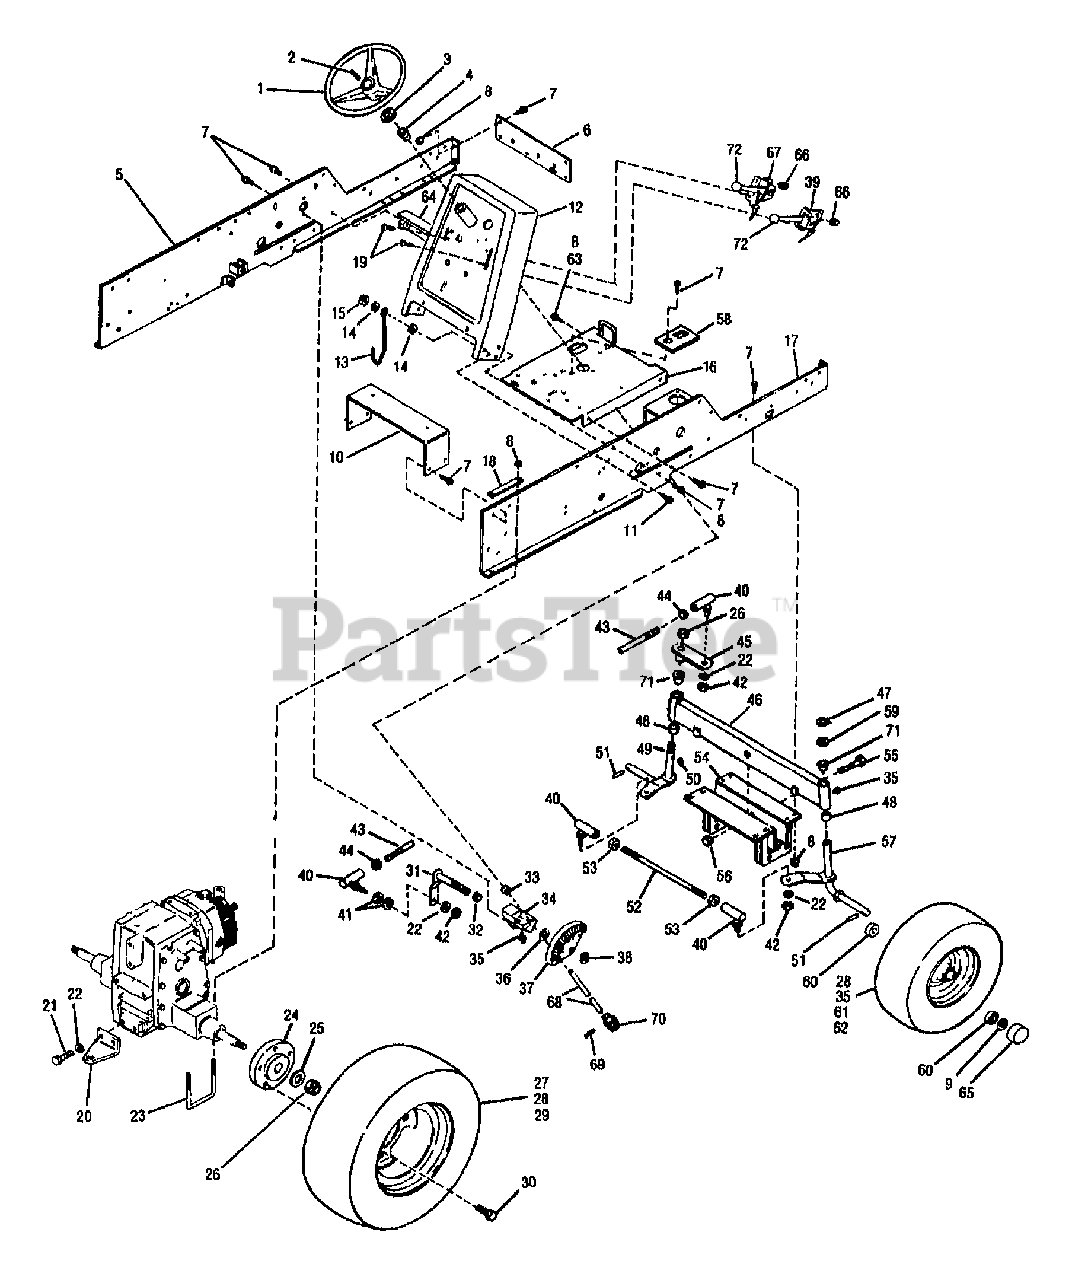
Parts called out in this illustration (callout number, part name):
1	WHEEL-STEERING
2	PIN-ROLL .25X2.25
3	WASHER-1.5X.755X.062
4	BEARING-STEERING
5	ASSM-FRAME LH
8	NUT-HFLK 3/8-16 ZP
9	WASHER-THRUST
10	SUPPORT-SEAT
11	SCR-HFLK 3/8-16X1.00 ZP
12	ASSM-INST PANEL
13	GUIDE-CABLE
14	WASHER-.986X.437X.083 ZP
15	NUT-H/LK 3/8-16
16	ASSM-SUPT BATTERY&GAS TANK
17	ASSM-FRAME RH
18	DOUBLER-REAR
19	SCR-TRUSS #10-24 X 5/8
21	SCR-HH 1/2-13X1.25 G5 ZP
22	WASHER-LK .5
23	BOLT-U
24	HUB-WHEEL
25	SPACER-1.812X.765X.179
26	NUT-H/LK 3/4-10
27	ASSM-WHEEL
28	STEM-VALVE
29	TIRE-23X8.50-12
30	BOLT-HUB
31	ASSM-STEERING A
32	SPACER-.938X.767X.562
33	BUSHING-FLANGE
34	BRKT-STEERING SUPT
35	FITTING-GREASE 1/4-28X2.00
36	WASHER-SHIM
37	GEAR-STEERING
38	RING-RETAINING EXT .694 ID
39	CONTROL-THROTTLE
40	JOINT-BALL
42	NUT-H/LK 1/2-20 ZP
43	ROD-STEERING
44	NUT-JAM
45	ARM-STEERING
46	ASSM-FRONT AXLE
47	RING-RETAIN EXT .707 ID
48	BEARING-BRONZE
49	ASSM-SPINDLE LH
50	KEY-WOODRUFF 3/16X1-1/8
51	PIN-ROLL .312X1.25
53	NUT-JAM
54	ASSM-AXLE SUPT
55	SCR-HH 5/8-11 G8 ZP
56	NUT-LOCK
57	ASSM-SPINDLE RH WHEEL
59	WASHER-THRUST
60	BEARING-BALL W/SEAL
61	ASSM-WHEEL
62	TIRE-16 X 6.50-8
63	BEARING-BALL W/SEAL
64	ASSM-FRAME SUPT
65	CAP-WHEEL
66	NUT W/LKWASHER 10-24 ZP
67	CHOKE-CONTROL
68	SHAFT-STEERING
69	PIN-ROLL .25X.937 ZP
70	GEAR-BEVEL PINION
71	BEARING-FLANGE
72	KNOB
